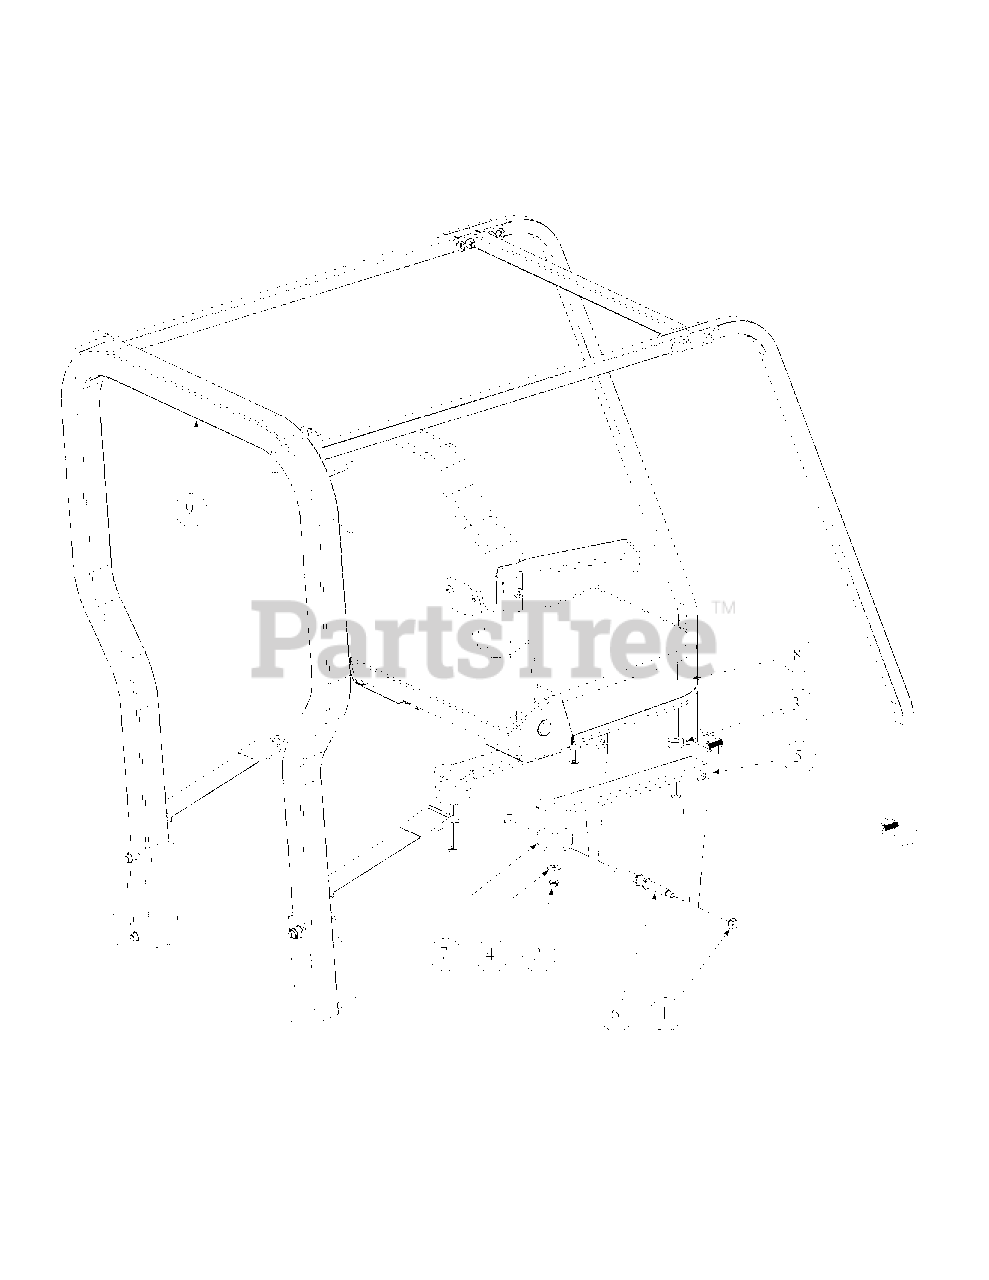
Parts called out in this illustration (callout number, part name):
1	Nut, Hex 3/8-16 Flange Lock
2	Lock Nut, Hex Flange, 5/16-18
3	Spacer, 0.345 ID x 1.50 OD x .41
4	Washer, .325 ID x .930 OD x .045
5	Mounting Bracket, Seat
6	Shoulder Screw, .50x2.345, 3/8-16
7	Grommet, 2.5 OD x 1.0 Long
8	Adjustable Seat, Black embossed, Forward Fold
9	ROPS Assembly
